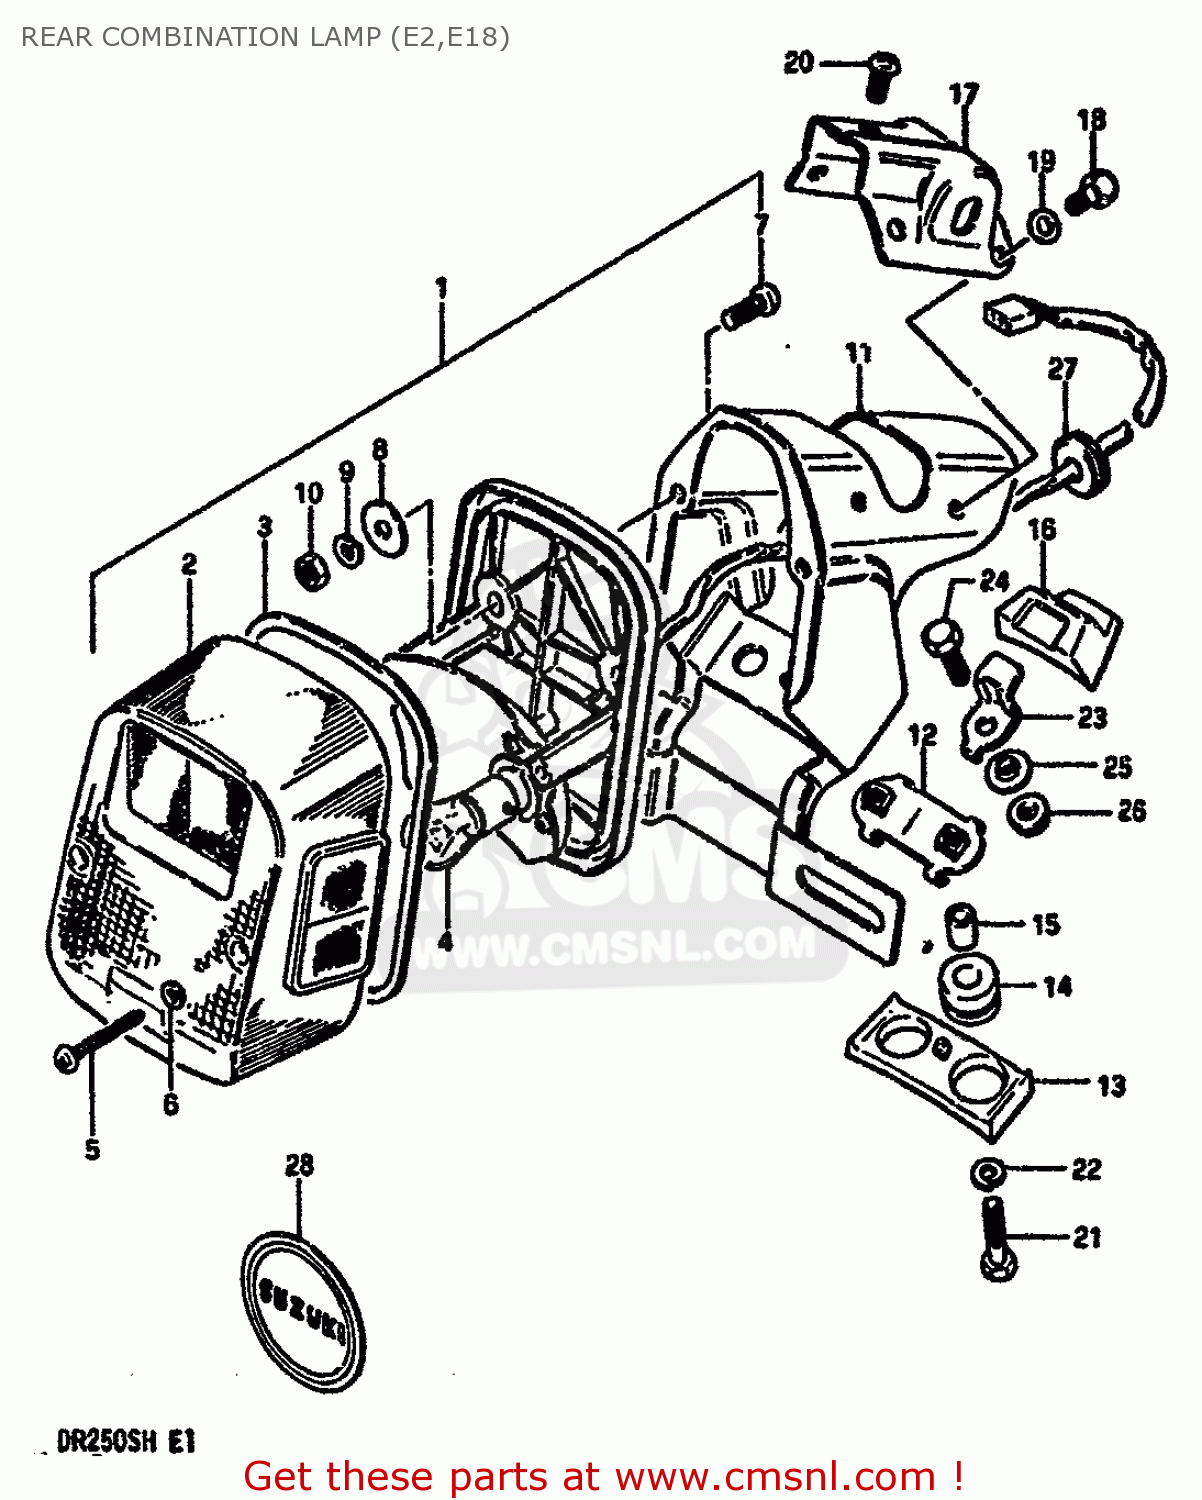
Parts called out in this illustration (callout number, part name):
1	LAMP UNIT,RR COMBNATION
2	LENS
3	GASKET (NAS)
4	BULB 12V21/5W
5	SCREW
6	GASKET (NAS)
7	SCREW
8	WASHER,REAR COMBINATION LAMP
9	LOCK WASHER
10	NUT
11	BRACKET UNIT
12	PLATE
13	CUSHION
14	CUSHION
15	SPACER
16	CUSHION,REAR COMBINATION LAMP
17	PLATE
18	BOLT
19	WASHER
20	SCREW 6X12
21	BOLT
22	WASHER,LOCK
23	PLATE,RR COMBINATION LAMP
24	BOLT
25	WASHER,LOCK
26	NUT
27	GROMMET
28	EMBLEM, REAR
